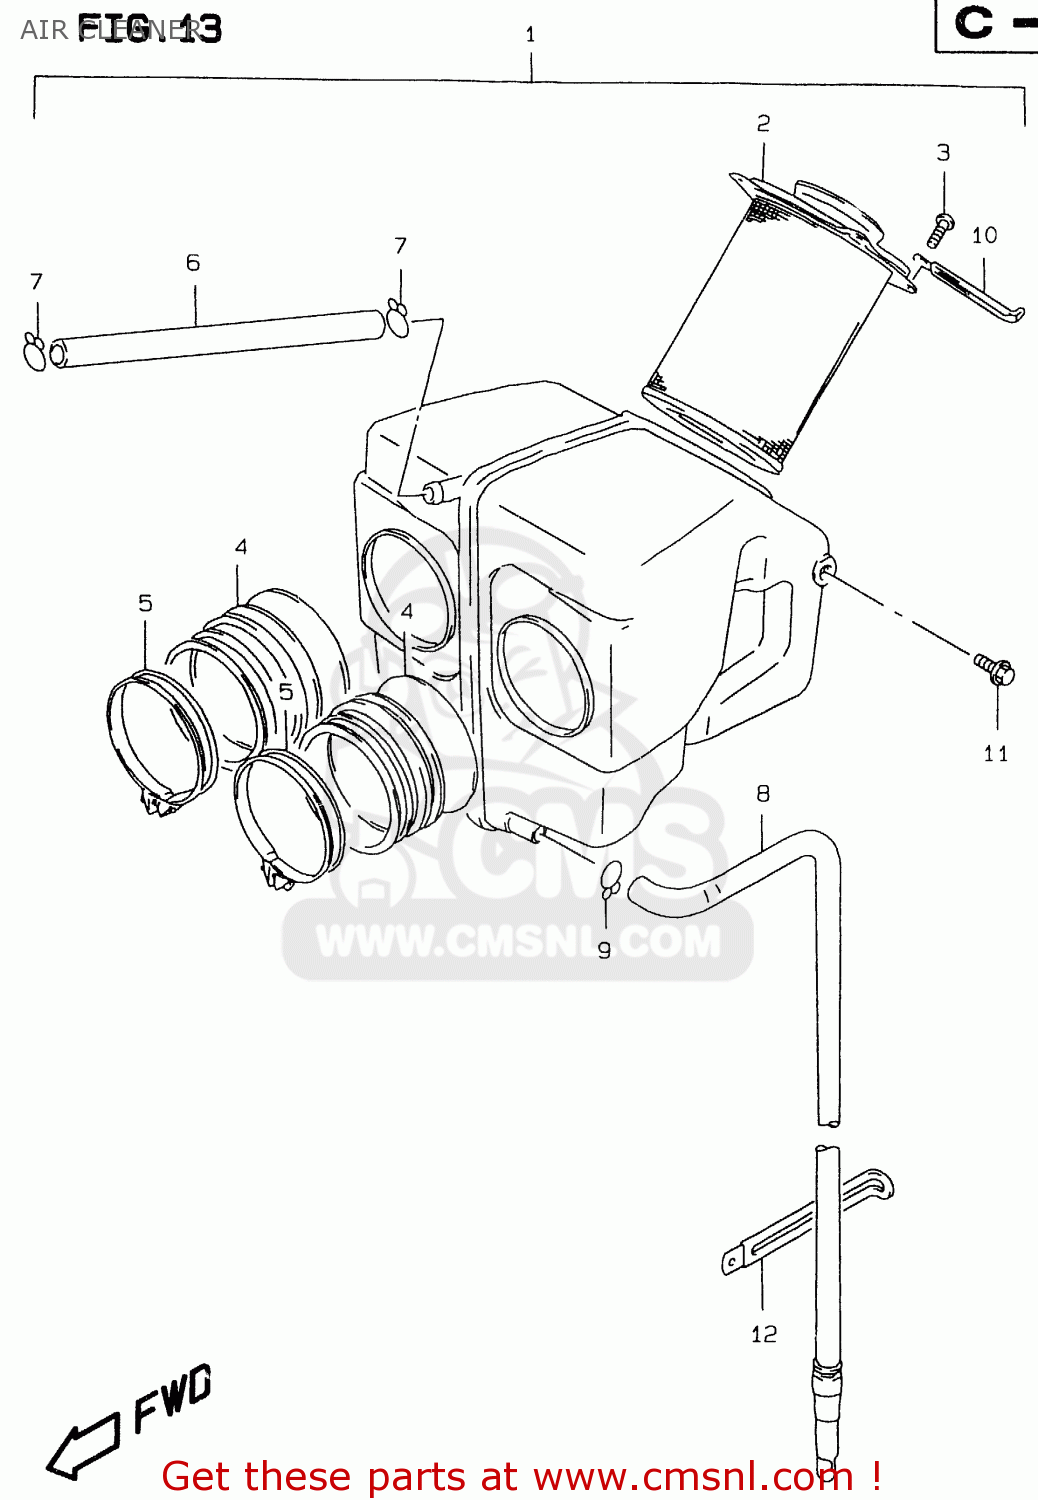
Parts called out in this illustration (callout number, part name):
1	CLEANER ASSY,A
2	FILTER,AIR
3	SCREW
4	TUBE,OUTLET
5	CLAMP
6	HOSE(11X15X600)
7	CLIP
8	TUBE,DRAIN
9	CLIP
10	CLAMP
11	SCREW
12	CLAMP(L:80)
